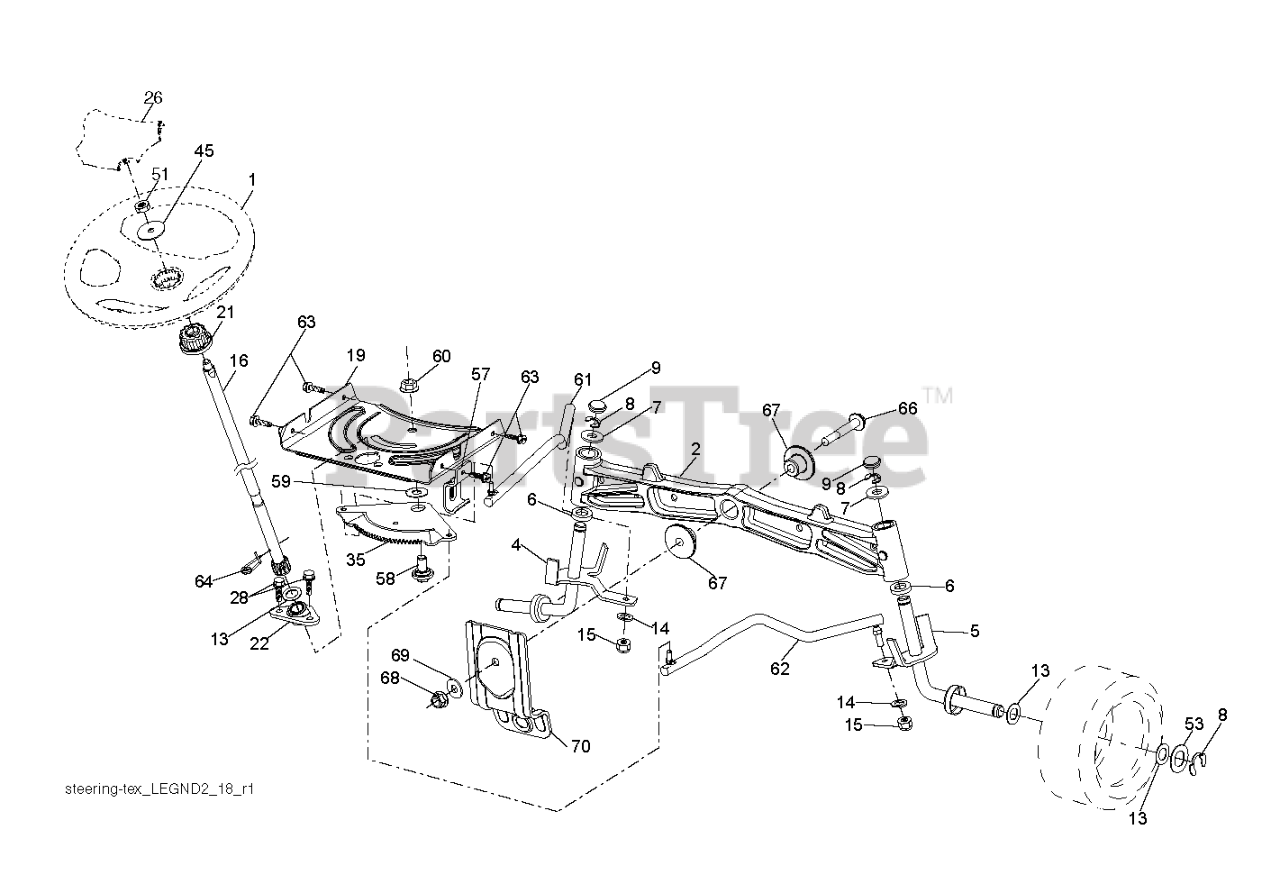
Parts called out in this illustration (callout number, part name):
1	RP WHEEL.STEER.HUSQ.PREM.OVMLD
2	AXLE.CAST.IRON
4	SPINDLE.WELDED.LH.15"TEX
5	SPINDLE.WELDED.RH.15"T
6	THRUST WASHER
9	CAP.SPINDLE.BLACK
14	WASHER, LOCK 3/8
15	NUT CROWNLOCK 3/8-24
16	SHAFT, STEERING
19	PLATE.STEER.DDL.NLT/NG
21	ADAPTER, WHEEL STNG..
22	STEERING.SUPT.LOWER.
26	RP INSERT.CAP.WHL.STRG.HUSQ.
28	SCREW, 3/8-16X3/4
35	GEAR.SECTOR.PLATE.DDL.
45	WASHER 9/16"ID, 2 3/8"OD
51	NUT.HEX.1/2-20
53	WASHER.HARDENED
57	BRKT.UPSTOP.GT/LT.TEX
58	BOLT.SHOULDER.SECTOR.P
59	WASHER.THURST.SECTOR.S
60	NUT FLANGE LOCK 5/8-11
61	DRAGLINK.LH.BALLSTUD.D
62	DRAGLINK.RH.BALLSTUD.D
63	SCREW
64	RETAINER.CLIP.SPRING.S
66	BOLT HEX FGHD 7/16-14 X 3 SERR
67	BUSHING.PM.FRONT AXLE
68	NUT.LOCK.FLANGE.7/16
69	WASHER.1.5X.505X.118
70	BRKT.DECK.SUSPENSION.F
